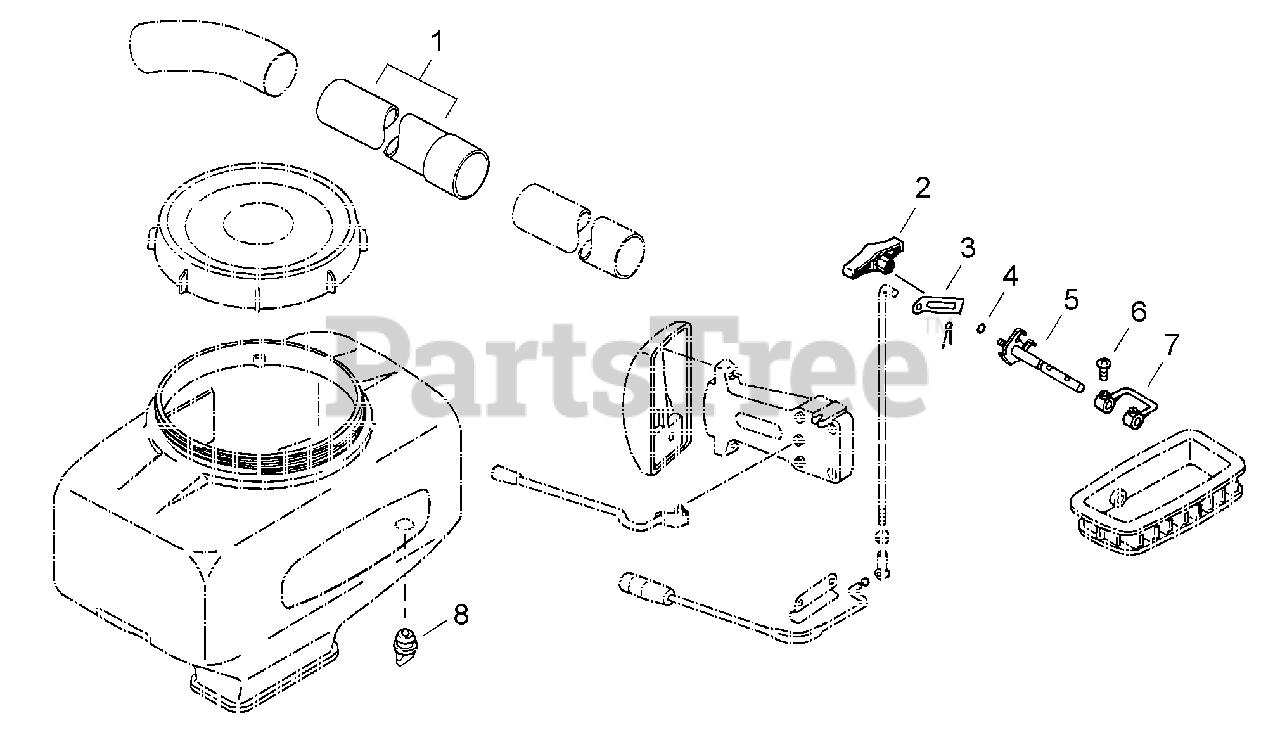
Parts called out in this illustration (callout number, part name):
1	TUBE, BLOWER - STRAIGHT
3	ARM, SHUTTER
4	O-RING - 7
5	SHAFT, SHUTTER
6	SCREW - 4X16
